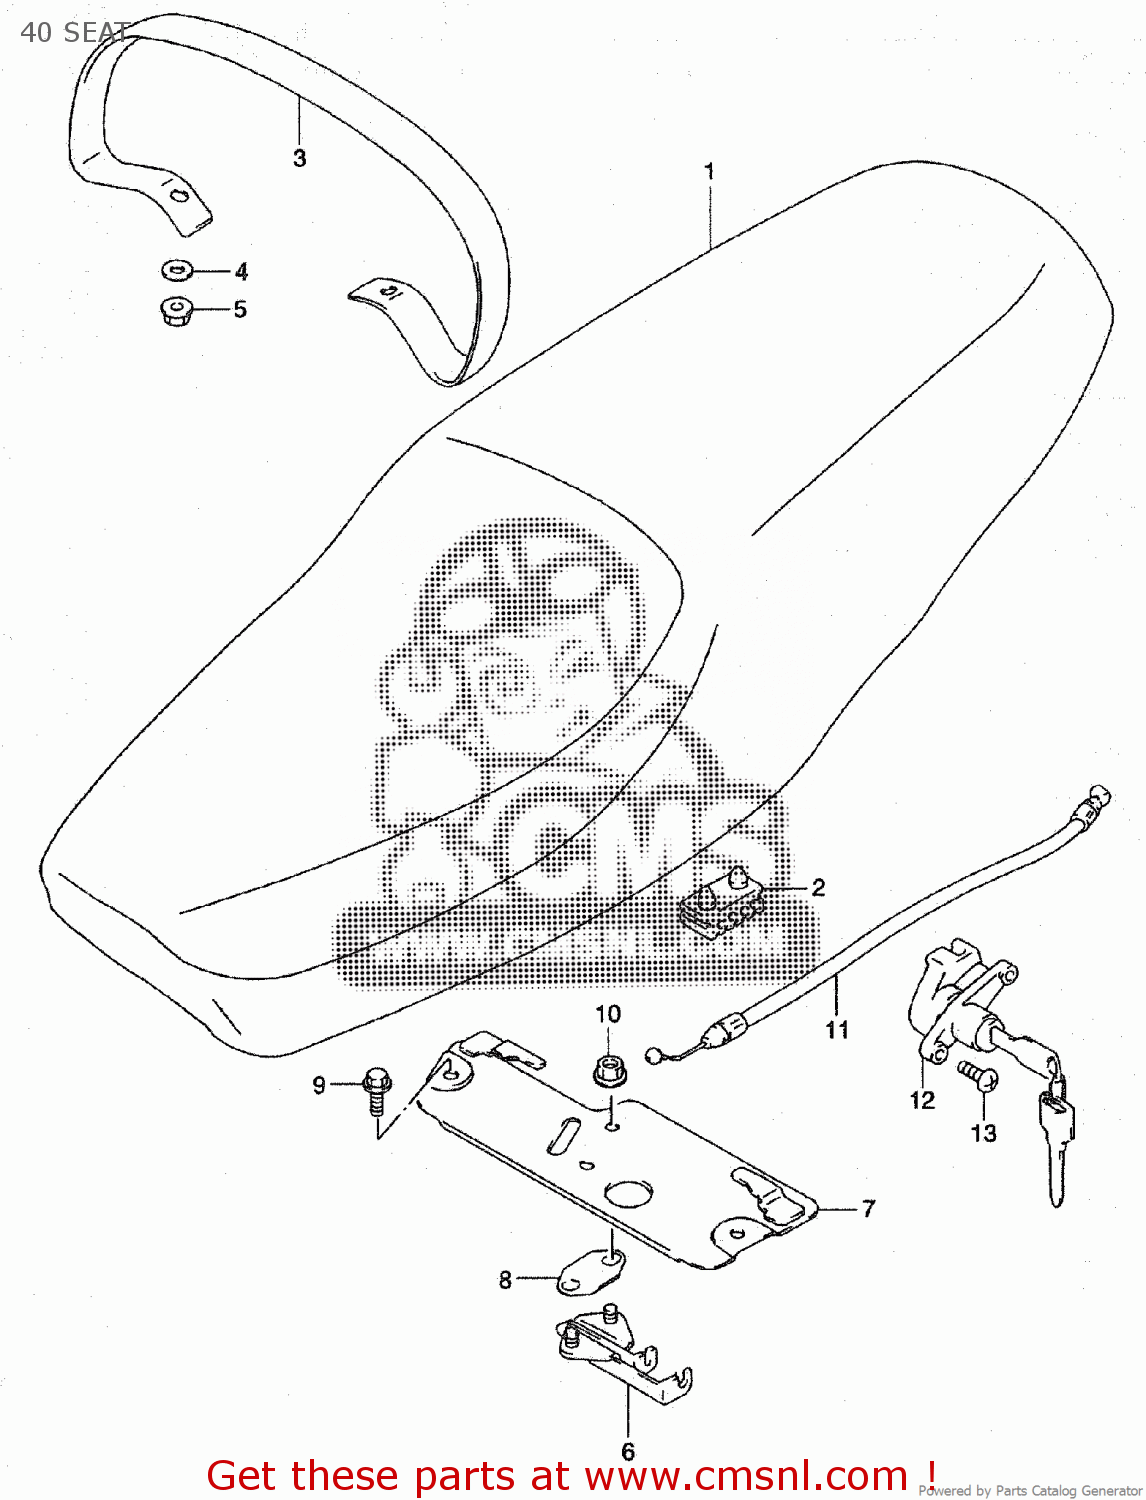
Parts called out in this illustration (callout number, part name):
2	CUSHION,SEAT
4	WASHER
5	NUT
6	BRACKET,SEAT SUPPORT
8	PLATE,SEAT SUPPORT BRKT
9	BOLT
10	NUT
12	LOCK SET,SEAT
13	SCREW(6X14)
